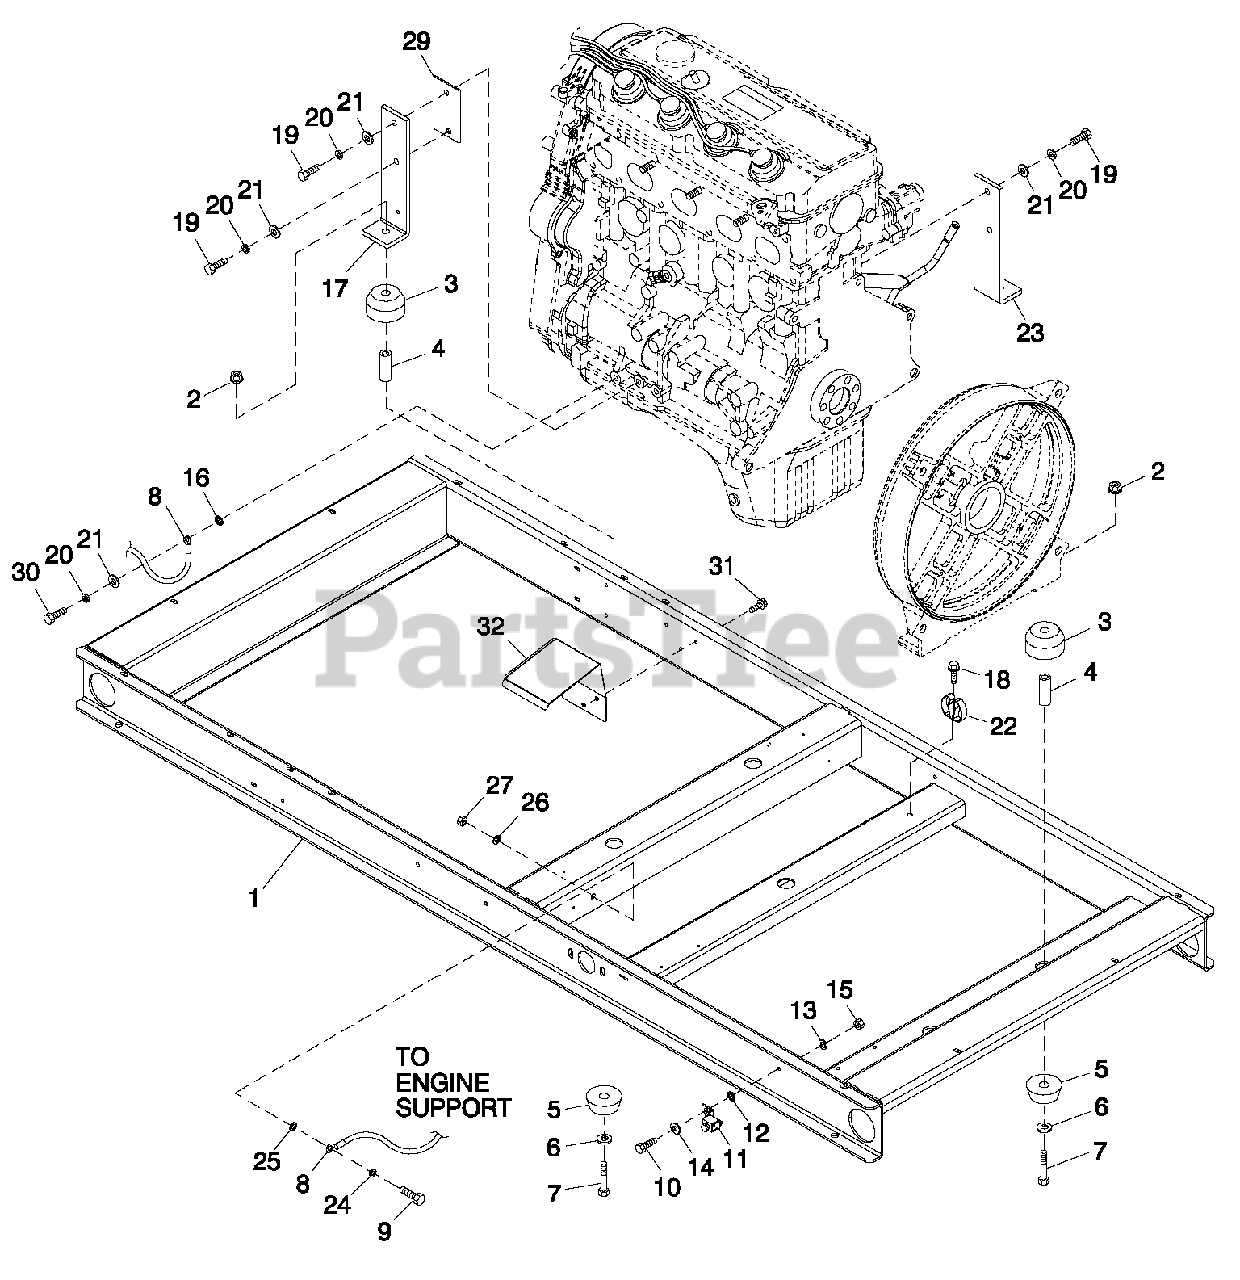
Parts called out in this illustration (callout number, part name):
1	WELDMENT FRAME 2.4L C2
2	NUT FLANGED HEX M12-1.75
3	DAMPENER VI B RATION 40 BLUE
4	SPACER .49 X .62 X 1.87 PWDR/ZNC
5	DAMPENER VI B RATION
6	WASHER FLAT M12
7	SCREW HHC M12-1.75 X 80 G8.8
8	ASSY WIRE 14.00"
9	SCREW HHC M8-1.25X 30 G8.8
10	SCREW HHC M6-1.0X 16 G8.8
11	LUG SLDLSS #2-#8X 17/64 CU
12	WASHER LOCK SPECIAL 1/4"
13	WASHER LOCK M6-1/4
14	WASHER FLAT M6-1/4 ZINC
15	NUT HEX M6 -1.0G8YEL CHR
16	WASHER SHAKEPROOF INT 3/8
17	SUPPORT LH ENGINE 2.4L
18	SCREW HHTT M4-0.7X8BP
19	SCREW HHC M10-1.25 X 30 G8.8
20	WASHER LOCK 7/16
21	WASHER FLAT 3/8-M10 ZINC
22	SPRING CLIP HOLDER .37-.62
23	SUPPORT RH ENGINE 2.4L
24	WASHER LOCK M8-5/16
25	WASHER LOCK SPECIAL 5/16
26	WASHER FLAT 5/16-M8 ZINC
27	NUT HEX M8-1.25 G8 CLEAR ZINC
29	SPACER ENGINE MOUNT (2.4L G1)
30	SCREW HHC M10-1.25 X 25 C8.8
31	SCREW HWHT M6-1 X 16 N WA Z/JS
32	HEAT SHIELD 2.4L G2
